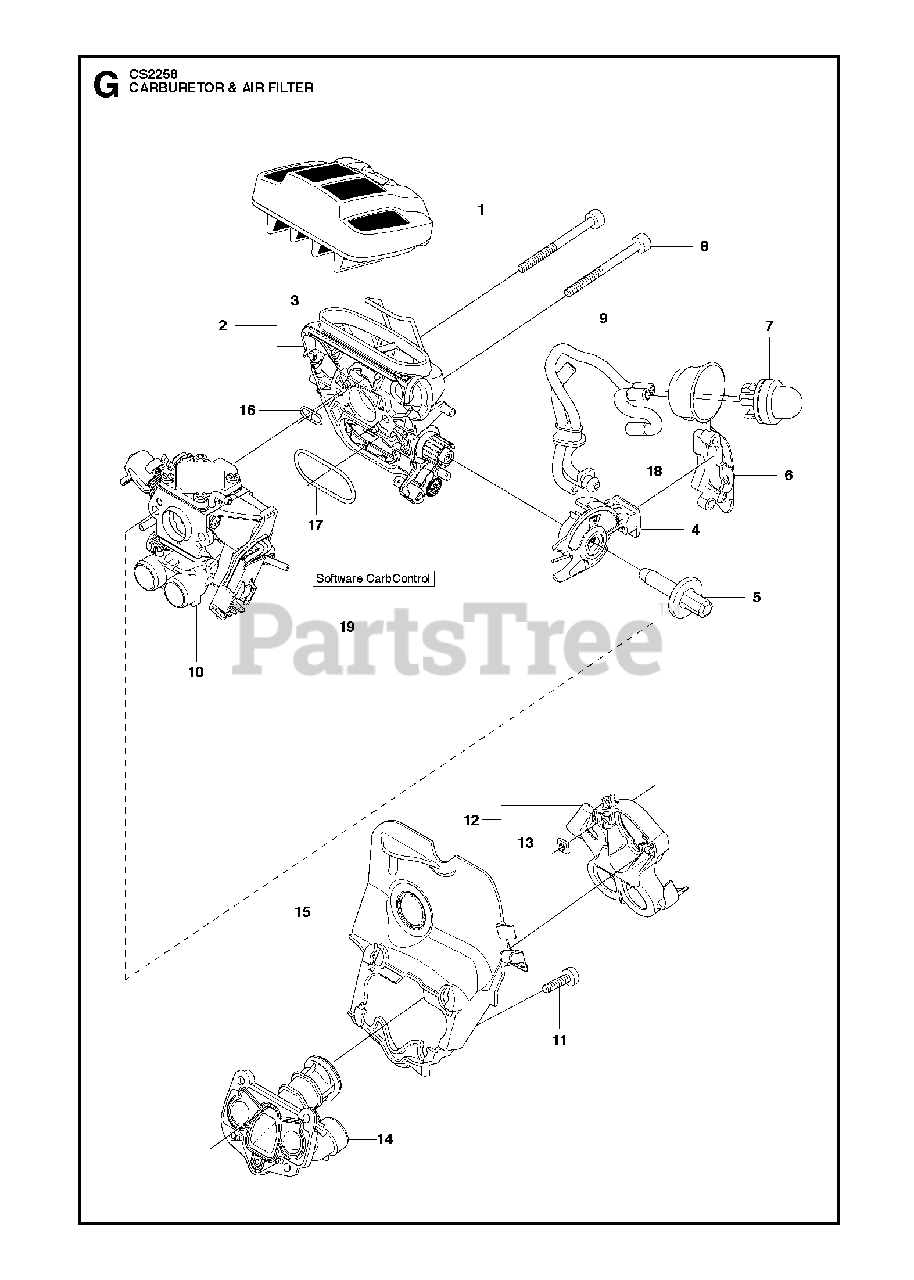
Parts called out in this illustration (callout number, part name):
1	AIR FILTER ASSY
2	RP FILTER HOLDER ASSY
2	FILTER HOLDER ASSY
3	SHACKLE
4	CHOKE CONTROL ASSY
7	AIR PURGE BUBBLE
9	FUEL HOSE
10	CARBURETOR KIT 555 AUTOTUNE
11	SCREW IHSCM
13	NUT
14	INLET PIPE
15	INTERMEDIATE WALL
18	FUEL HOSE
